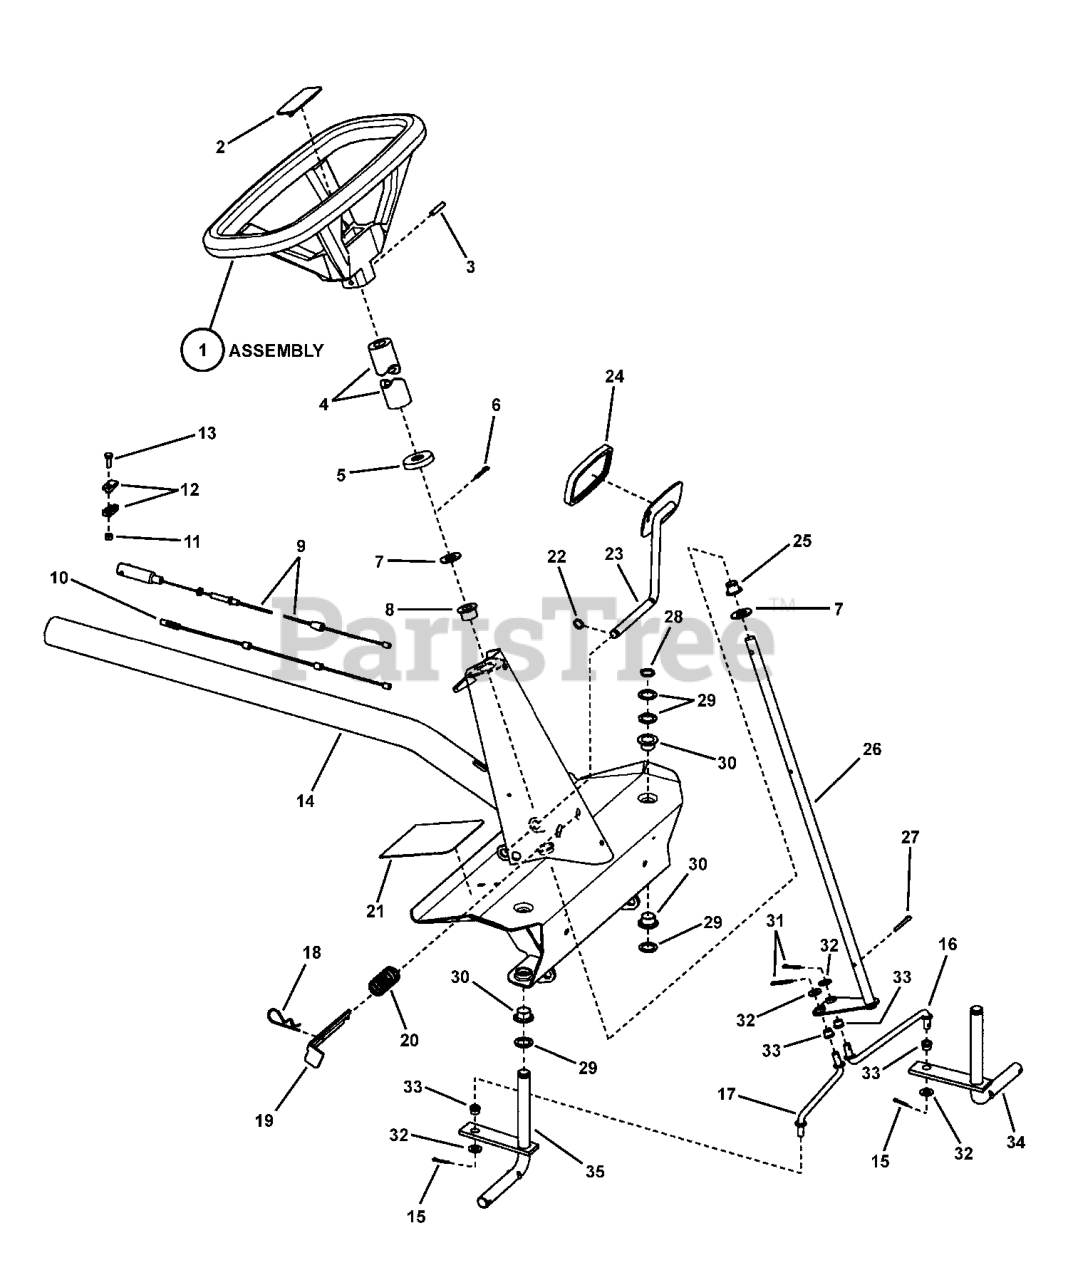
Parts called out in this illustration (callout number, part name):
1	ASSEMBLY, Steering Wheel (for 5/8" shaft)
2	PLATE, Center, Steering Wheel
3	ROLL PIN, 1/4 x 1-1/2"
4	FOAM COVER, Steering Shaft
5	COVER, Steering Shaft
6	PIN, 3/16 x 1" Cotter
7	WASHER, .66 x 1.31 x .09 Flat
8	BUSHING, Nylon
9	CABLE, Brake, Snap-In
10	CABLE, Clutch/Brake (54.32" long)
11	NUT, 1/4-20 Hex Center Lock, GR 5 or B
12	CONNECTOR, Cable
13	SCREW, 1/4-20 x 3/4" Hex Head Cap, GR 5
14	WELDMENT, Front Axle, Narrow
15	PIN, 1/8 x 3/4" Cotter
16	TIE ROD, Left Hand (7.41" long)
17	TIE ROD, Right Hand (7.41" long)
18	HAIR PIN, 2-1/4"
19	LATCH, Parking Brake
20	SPRING, Parking Brake Latch
21	FOOT PAD, Short (5.5" x 4.7")
22	RING, 1/2" External Retaining (Heavy Duty)
23	WELDMENT, Clutch Pedal
24	PAD, Pedal
25	BUSHING, Nylon
26	WELDMENT, Steering Shaft
27	PIN, 3/16 x 1-1/2" Cotter
28	RING, 5/8" External Retaining
29	WASHER, .77 x 1.13 x .06 Flat
30	BEARING, Nylon
31	PIN, 5/32 x 1" Cotter
32	WASHER, 3/8" Flat SAE
33	BUSHING, Tie Rod
34	WELDMENT, King Pin, Left Hand
35	WELDMENT, King Pin, Right Hand
